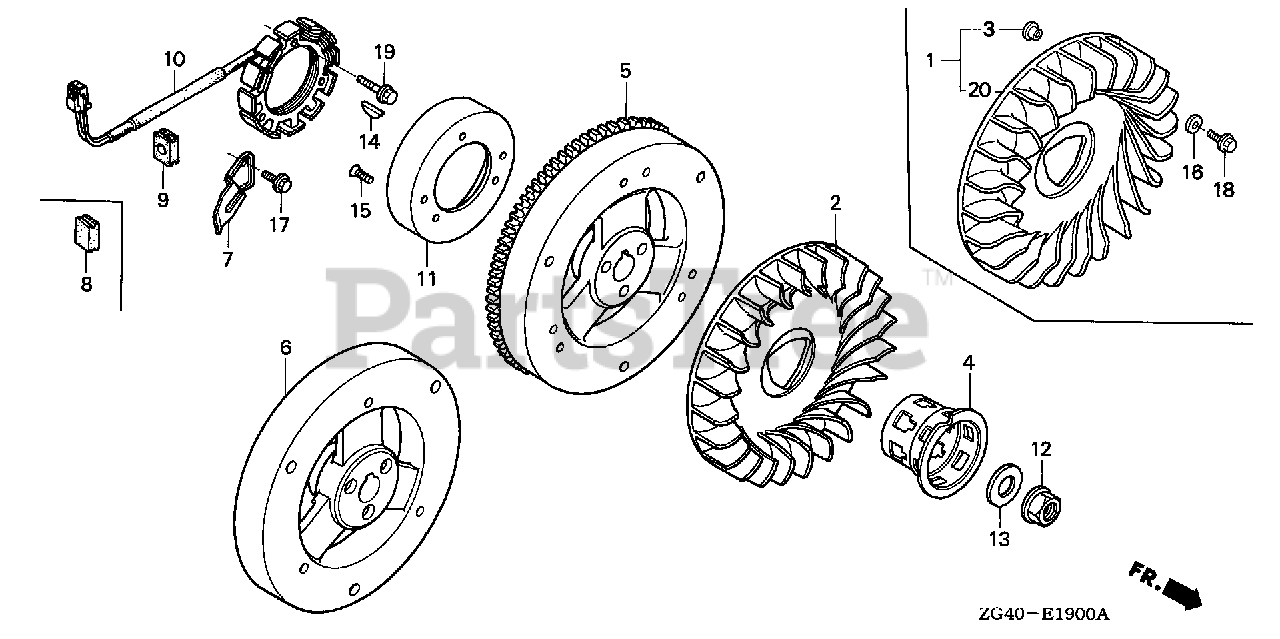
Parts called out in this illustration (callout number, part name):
2	FAN, COOLING
4	PULLEY, STARTER
6	FLYWHEEL (NOT AVAILABLE)
6	FLYWHEEL (N3)
8	GROMMET, WIRE
12	NUT, FLANGE (20MM)
13	WASHER (20MM)
14	KEY, WOODRUFF (50X7)
